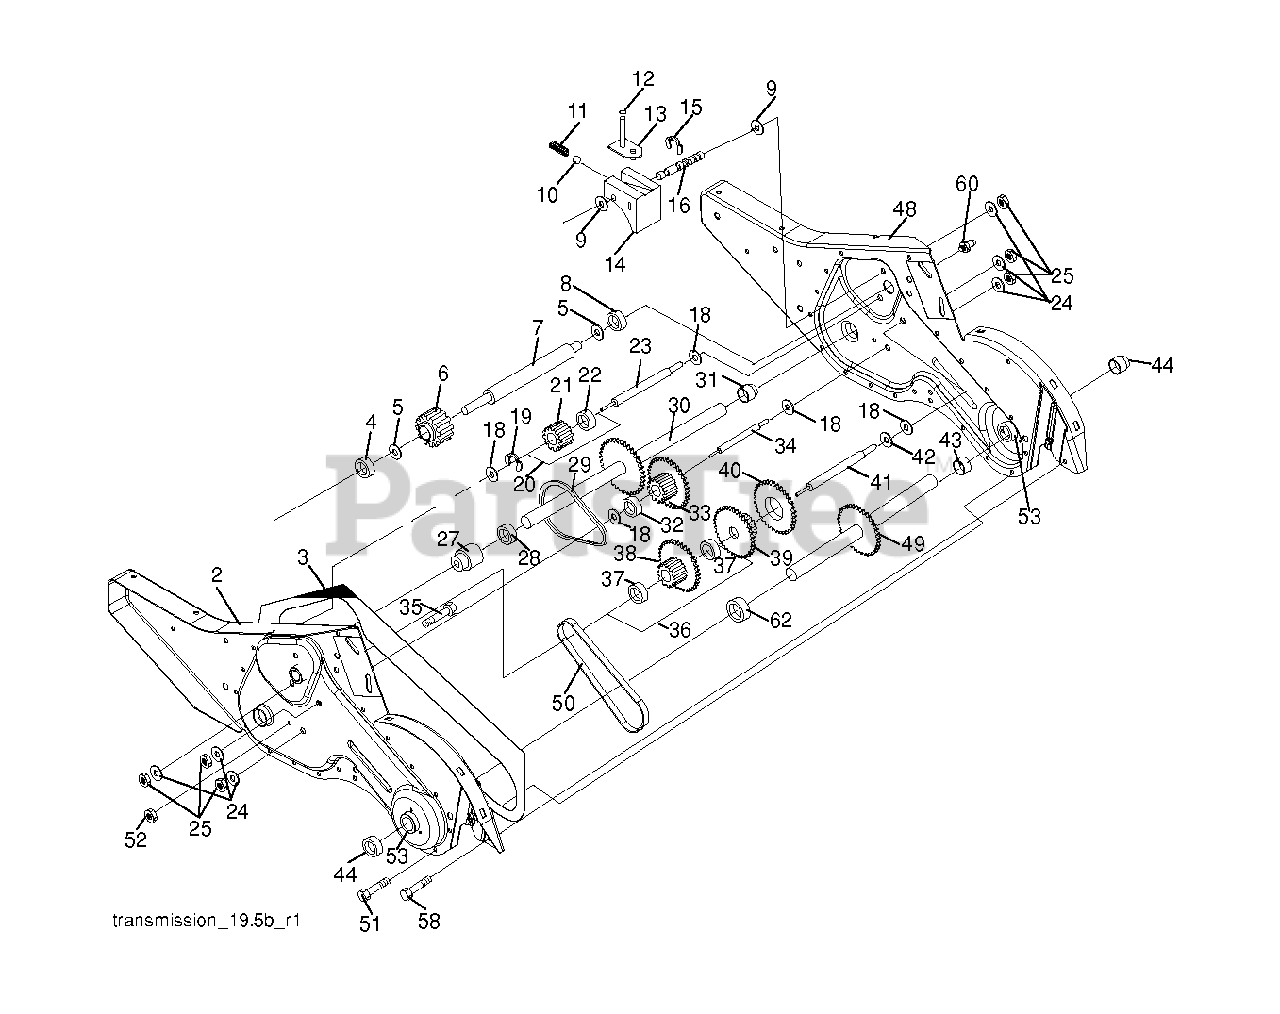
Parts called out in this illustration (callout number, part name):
1	TRANSMISSION ASM.
2	GEARCASE.ASM.CRT.LH.W/BEARING
3	GASKET, GEARCASE
4	NEEDLE BRNG LT
5	THRUST WASHER
6	GEAR.PINION.INPUT
7	SHAFT.INPUT."D".TILLER
10	BALL, STEEL
11	SPRING-SHIFT CRT
14	SHIFT FORK TI
16	SHAFT.SHIFTER.TILLER
20	GEAR ASSY CRT
21	GEAR-REV IDLR CRT
22	NEEDLE BEARING TI
24	LOCKWASHER
27	BEARING, SHAFT LH CRT
30	GROUND SHAFT ASS'Y
31	BEARING, SHAFT RH CRT
33	SPRCKT 8 GEAR CRT
34	SHAFT.SECONDARY.REDUCTION.CRT
35	SCRW WHIZ LOK CRT
36	SPROCKET ASS'Y W/BRG
37	BEARING
38	SPROCKET, TINE
39	GEAR TI
41	SHAFT.REDUCTION.TILLER
44	SEAL ASM, OIL
48	GEARCASE.ASM.CRT.RH.W/BEARING
49	SHAFT.ASM.TINE
51	SCREW
58	BOLT SHOULDER 1/4-20 UNC X.875
60	FITTING.GREASE.TAPERED
